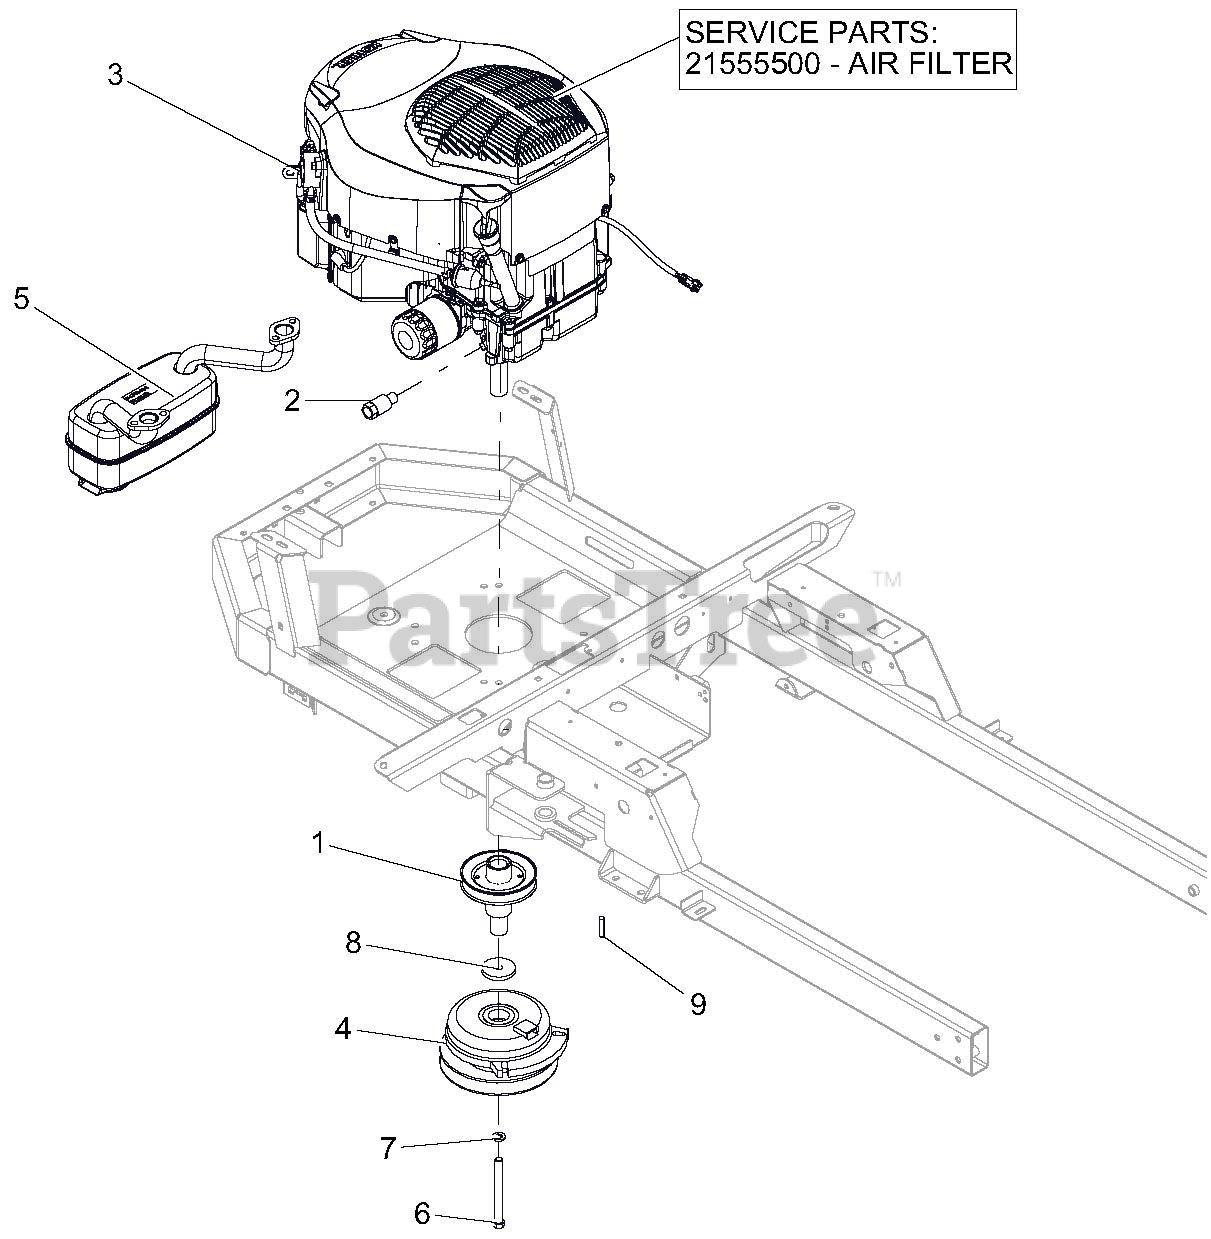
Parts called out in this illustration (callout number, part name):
1	WLDMT, DRIVE SHEAVE
2	DRAIN, OIL
3	ENGINE, KOHLER 24HP TWIN
3	AIR CLEANER, KOHLER
4	CLUTCH,105FTLB MONOPOLE 6.83"
5	MUFFLER, KOHLER TWIN
6	BLT-HEX .44-20X4.50 GR8 YWZC
7	@WSHR-LK .44X.109 REG YWZC
8	WSHR-FL-STL .469X2.00X.25 YWZC
9	KEY-SQ .25 X 1.25 X .25 SAE
